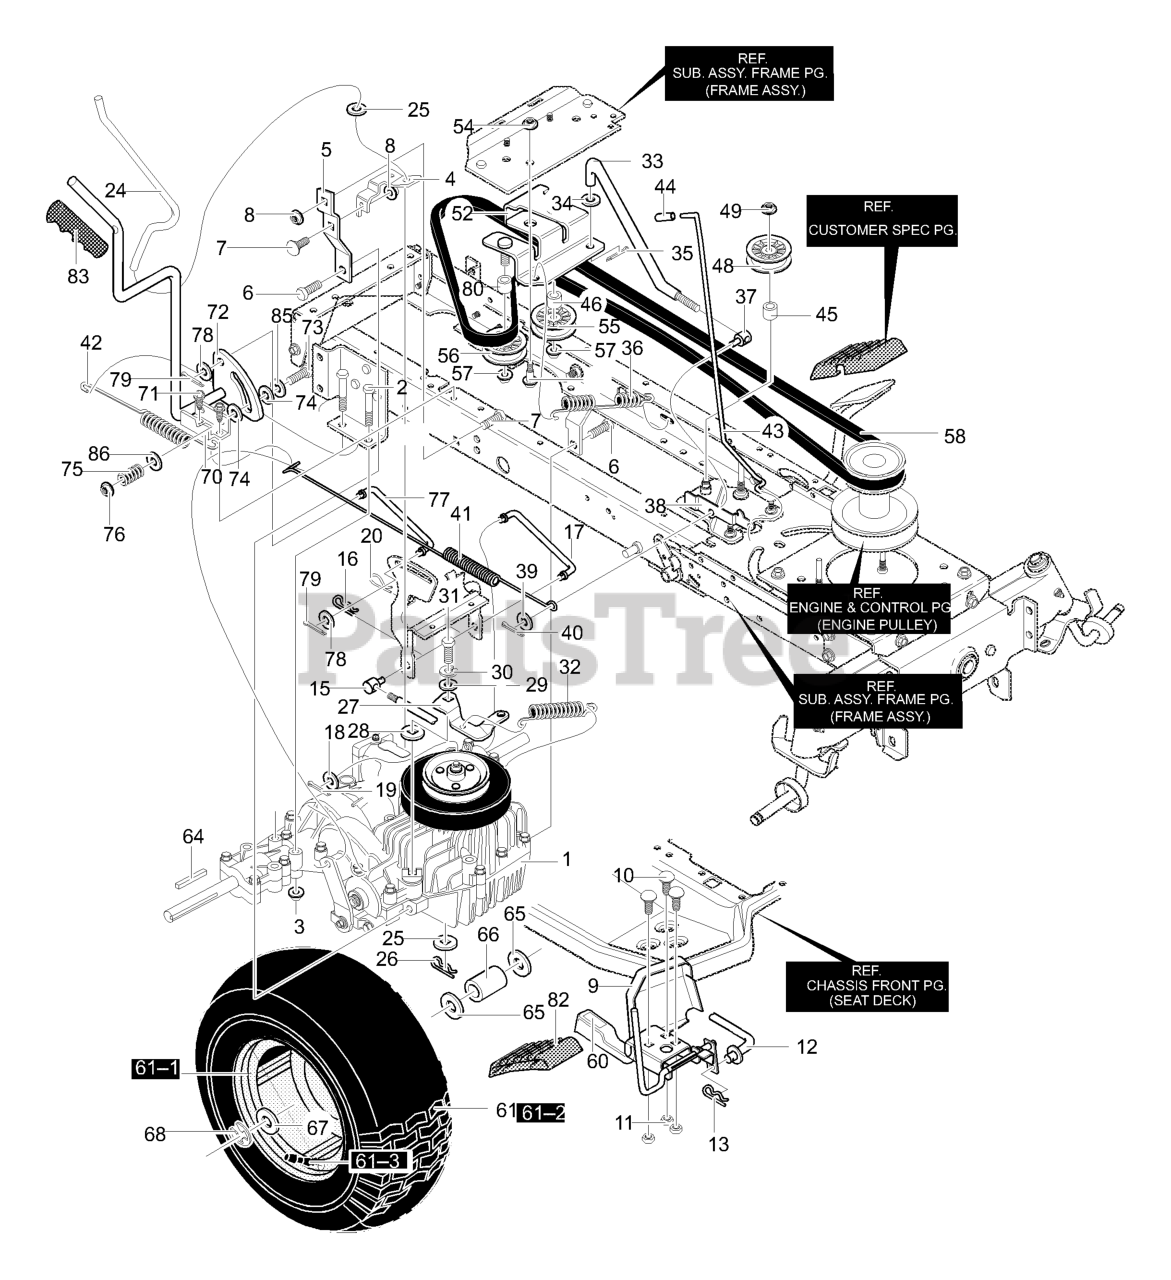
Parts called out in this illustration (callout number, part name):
1	Transaxle, VST205 **
2	Screw, 5/16-18 x 2.50
3	Nut, 5/16-18 Wdfllk
4	Bracket, Disconnect
5	Torque Strap
6	Screw, 5/16-18 x 0.75
7	Bolt, 5/16-18x.63
8	Nut, 5/16-18 Wdfllk
9	Pedal Assy., Hydro
10	Bolt, 5/16-18x.75
11	Nut, 5/16-18
12	Rod, Pedal Link
13	Hair Pin
15	Adjust Nut 1/2-13
16	Hair Pin
17	Rod Hydro Link
18	Flat washer
19	Cotter Pin
20	Hair Pin
24	Rod, Disconnect
25	Washer, Flat
26	Pin, Cotter
27	Arm Disconnect
29	Flat washer
30	Washer
31	Screw, 1/4-28x.75
32	Spring, Extension
33	Rod, Clutch
34	Flat washer
35	Cotter Pin
36	Spring, Clutch
37	Nut, Adjusting
38	Latch, Park Brake
39	Flat washer
40	Cotter Pin
41	Spring, Extension
42	Spring, Tension
43	Park Brake Rod
45	Spacer 1/2 to 17MM
46	Spacer 1/2 to 17MM
48	Pulley, Idler
49	Nut, 3/8-16
52	Asm., Bracket Idler
53	Bolt, 3/8-16
54	Nut, 3/8-16
55	Pulley, Idler
56	Pulley, Idler
57	Nut, 3/8-16
58	Belt, Motion Drive
60	Pad, Toe Sandpaper
61	Tire & Rim
61-1	Valve Stem
64	Key, Square
65	Flat washer
66	Spacer .87x1.78
67	Flat washer
68	Ring, E
70	Bracket, Mount Hand Ctrl
71	Screw, 5/16-18 x 0.75
72	Assy., Lever Hand Ctrl
73	Bolt, HHSH 5/16-18
74	Washer, Friction
75	Spring, Compression
76	Nut, 5/16-18
77	Link, Cruise Control
78	Flat washer
79	Cotter Pin
80	Spacer, 1/2 to 17MM
82	Pad, Speed Ctrl Pedal
85	Flat washer
86	Flat washer
